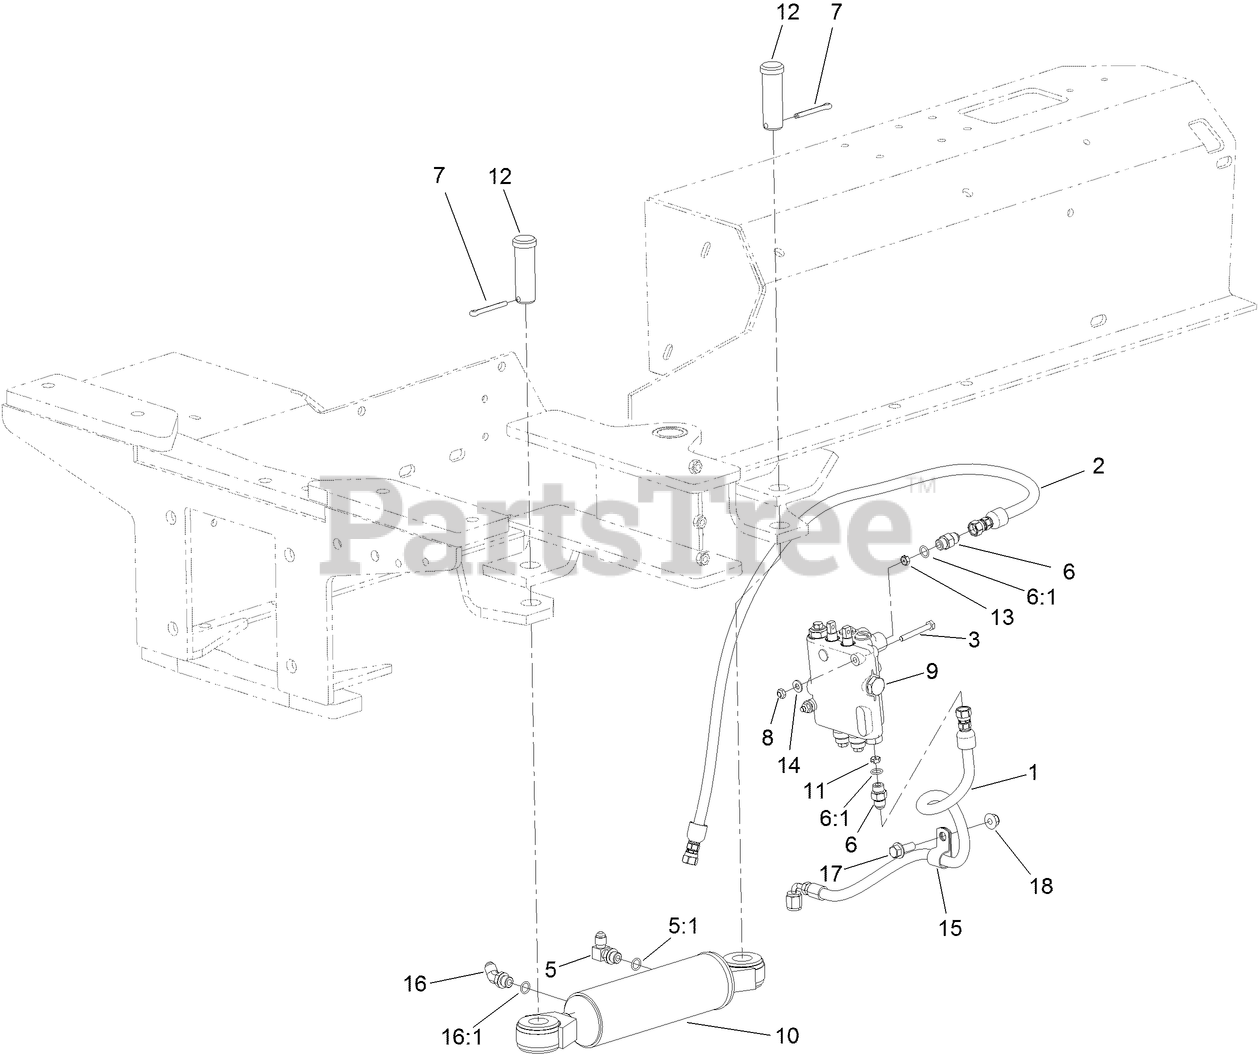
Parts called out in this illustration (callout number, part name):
1	HOSE ASM
2	HOSE ASM
3	SCREW-HH
5	FITTING-ELBOW, 90 DEG
5:1	O-RING
6	FITTING-STRAIGHT
6:1	O-RING
7	PIN-COTTER
8	NUT-LOCK, CONE
9	HYD STEERING VALVE ASM
10	HYD CYLINDER ASM
11	PLATE-ORIFICE
12	PIN-CLEVIS
13	PLATE-ORIFICE
14	WASHER-FLAT
15	CLAMP-R
16	FITTING-ELBOW, 45 DEG
16:1	O-RING
17	SCREW-HHF
18	NUT-HF, NI
